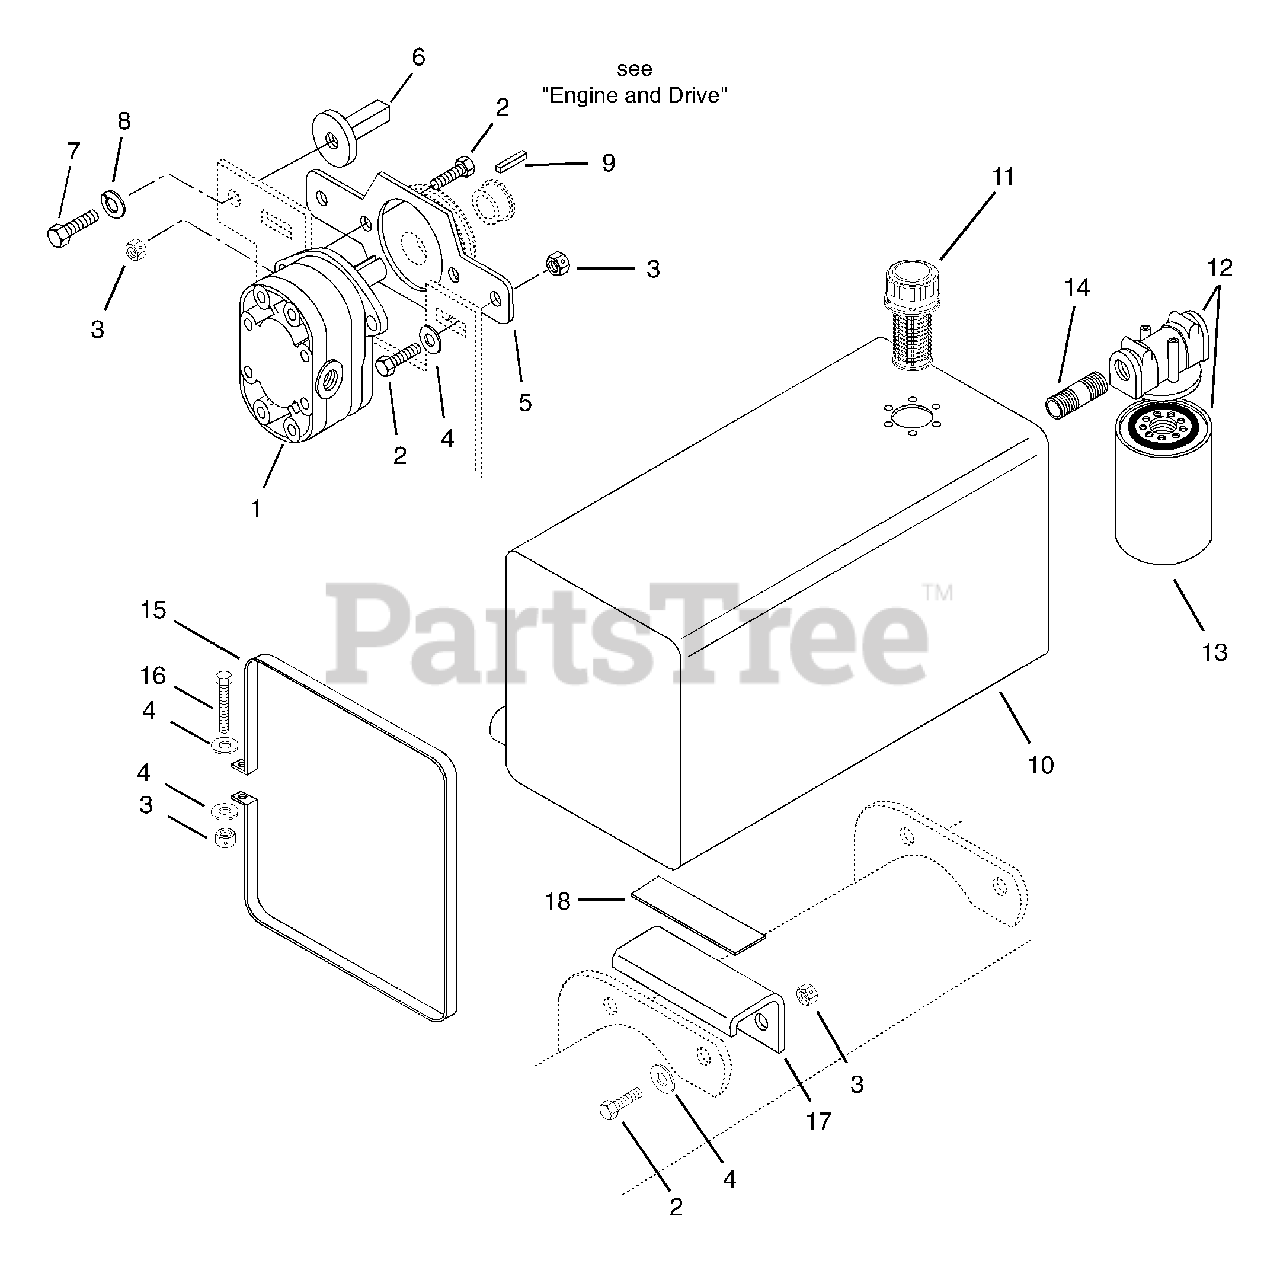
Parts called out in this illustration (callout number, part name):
1	Pump-Hydraulic
2	Bolt-Hex .38-16 x 1.25 Grade 5
3	Nut-Locking-Center .38-16
4	Washer-Flat-Steel .438 x 1.00 x .083
5	Bracket-Hydraulic Pump
6	Adjustment Cam Weldment
7	Bolt-Hex .50-13 x 2.00 Grade 5
8	Washer-Locking .50 x .125
9	Key-Square .250 x .375 x 1.25
10	Hydraulic Tank Weldment
11	Filler Cap Assembly
12	Filter
13	Replacement Filter Element
14	Nipple-Standard Pipe
15	Strap-Hydraulic Tank
16	Bolt Hex .38-16 x 3.00 Grade 5
17	Mount-Tank
18	Gasket
